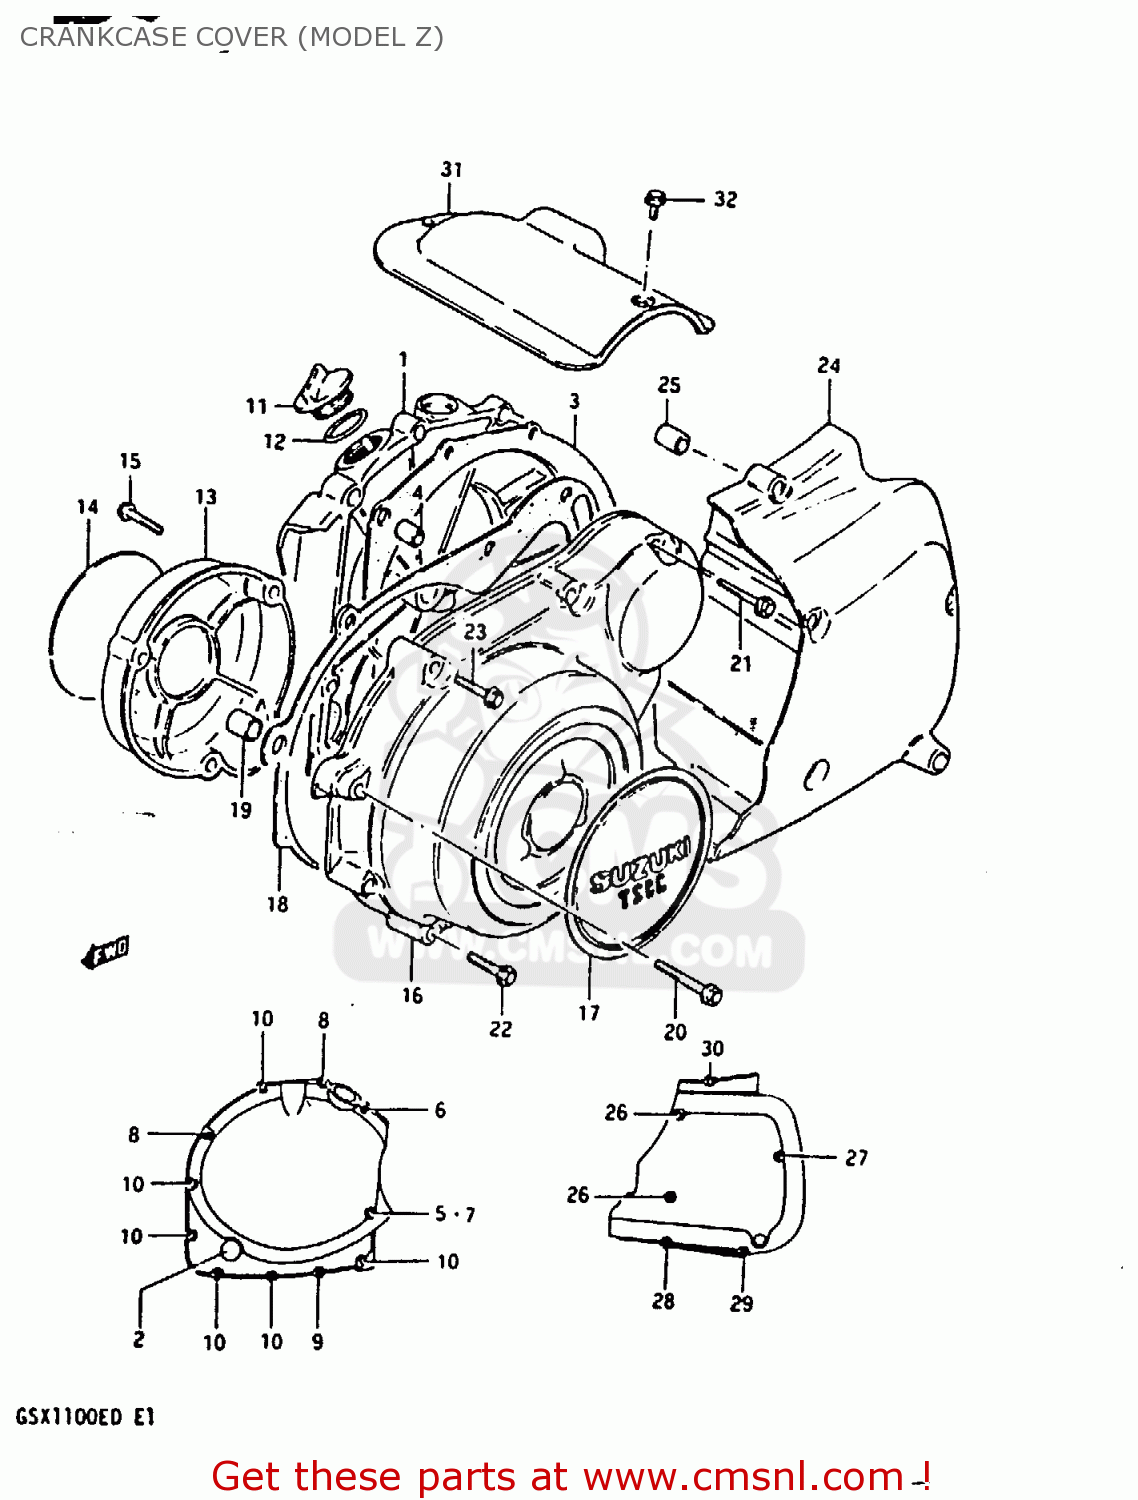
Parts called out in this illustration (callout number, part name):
1	COVER,CLUTCH
2	LENS,OIL LEVEL CHECK
3	GASKET,CLUTCH COVER (MCA)
4	PIN
5	GASKET (NAS)
6	BOLT (6X40)
7	BOLT (6X35)
8	BOLT (6X30)
9	BOLT
10	BOLT (6X20)
11	CAP
12	O RING(D:2.2,ID:32)
13	COVER,CONTACT BREAKER
14	EMBLEM
15	BOLT (5X30)
16	COVER,MAGNETO
17	EMBLEM,MAGNETO COVER
18	GASKET,MAGNETO COVER (MCA)
19	PIN
20	BOLT
21	BOLT (6X40)
22	BOLT (6X35)
23	BOLT (6X30)
24	COVER,ENGINE SPROCKET
25	PIN
26	BOLT 6X95
27	BOLT (6X85)
28	BOLT (6X70)
29	BOLT (6X55)
30	BOLT (6X30)
31	COVER,STARTER MOTOR
32	BOLT
